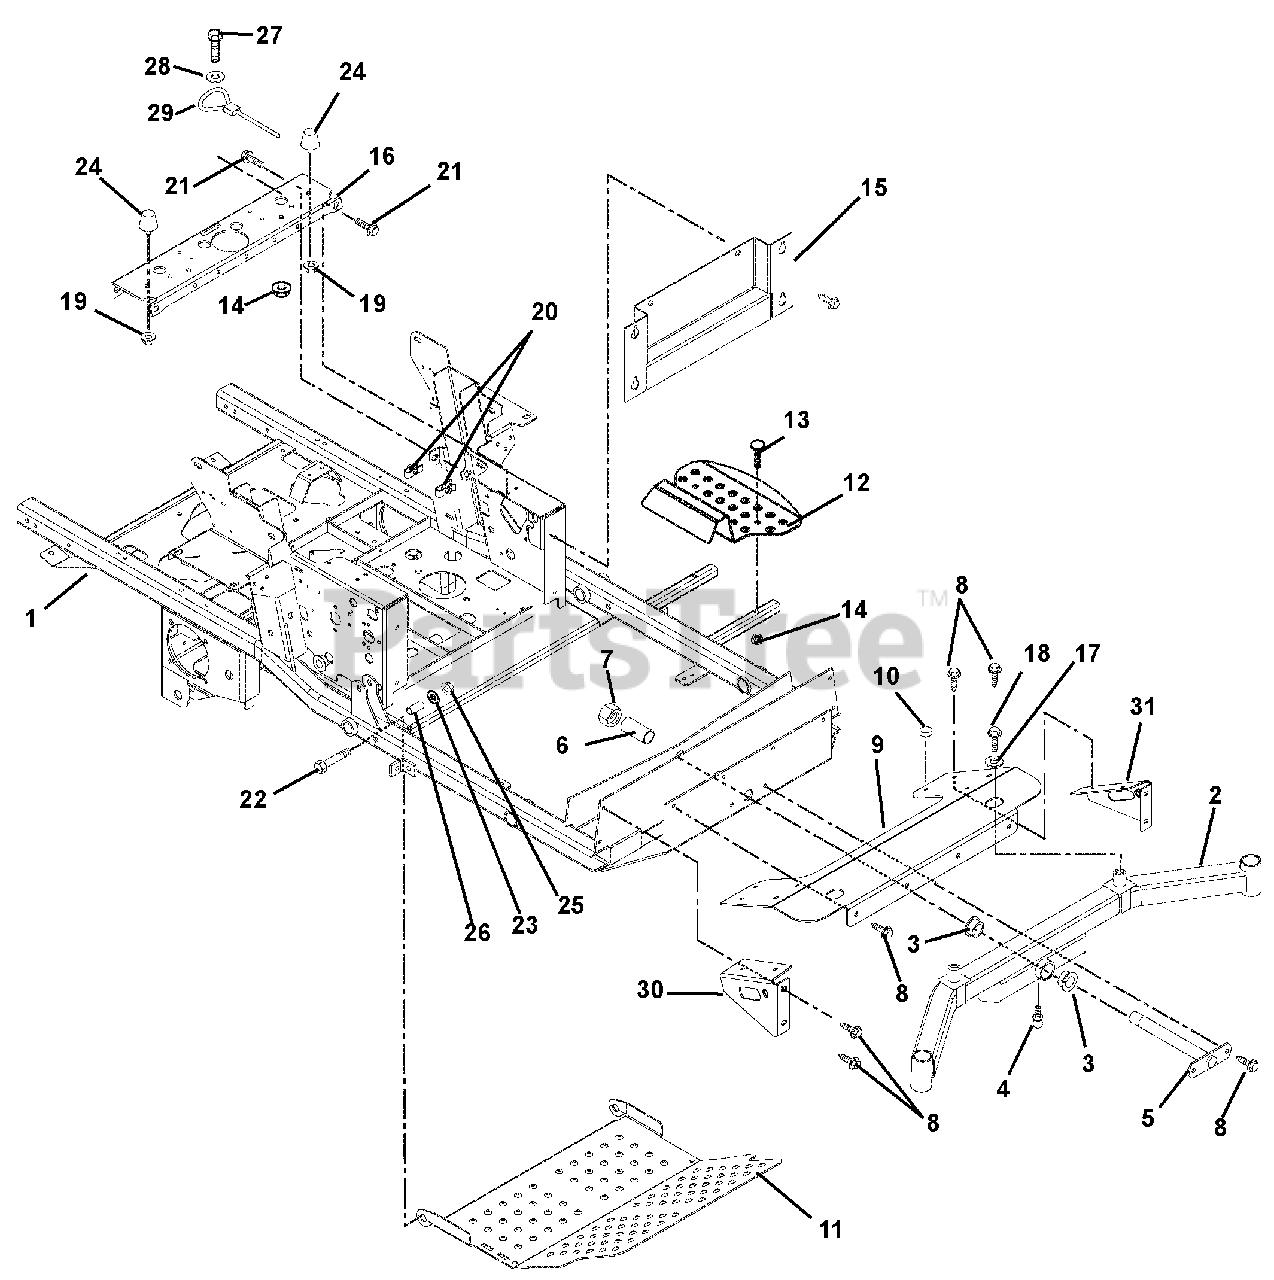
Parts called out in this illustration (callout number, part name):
1	Weldment, Frame
2	Weldment, Axle
3	Bushing, Flange 1.02 x 1.385 x .75 x 1.75
4	Fitting, Lube 45 Degree GM411031
5	Pin, Axle
7	Nut, Locking Nylon 1.00-14
8	Screw, Tapping .38-16 x .75
9	Axle Cover
10	Button, Rubber
11	Panel, Inspection
12	Step, Ingress
13	Bolt, Round Head Square Neck .31-18 x 1.75 Grade 5
14	Nut, Locking Top Flange .31-18
15	Plate, Kick
16	Channel, Cross
17	Washer, Flat Steel .640 x 1.81 x .25
18	Bolt, Hex .50-20 x 1.00 Grade 5
19	Nut, Locking Flange .312-18
20	Nut, Retainer .375-16 x .37
21	Bolt, Serrated Hex Flange Washer Head .38-16 x 1.00
22	Bolt, Hex .50-13 x 3.25 Grade 5
23	Washer, Flat Steel .563 x 1.38 x .109
25	Nut-Locking-Top-Flange .50-13
26	Bushing, Flange .515 x .75 x .275 x 1.12
27	Bolt, Hex .31-18 x .75 Grade 5 (992148, 149, 150, 151, 152, 153, 154, 155, 157, 159)
28	Washer, Flat Steel .344 x 1.25 x .135 (992148, 149, 150, 151, 152, 153, 154, 155, 157, 159)
29	Cable, Seat Prop. (992148, 149, 150, 151, 152, 153, 154, 155, 157, 159)
30	Weldment, RH Axle Cover Support
31	Weldment, LH Axle Cover Support
